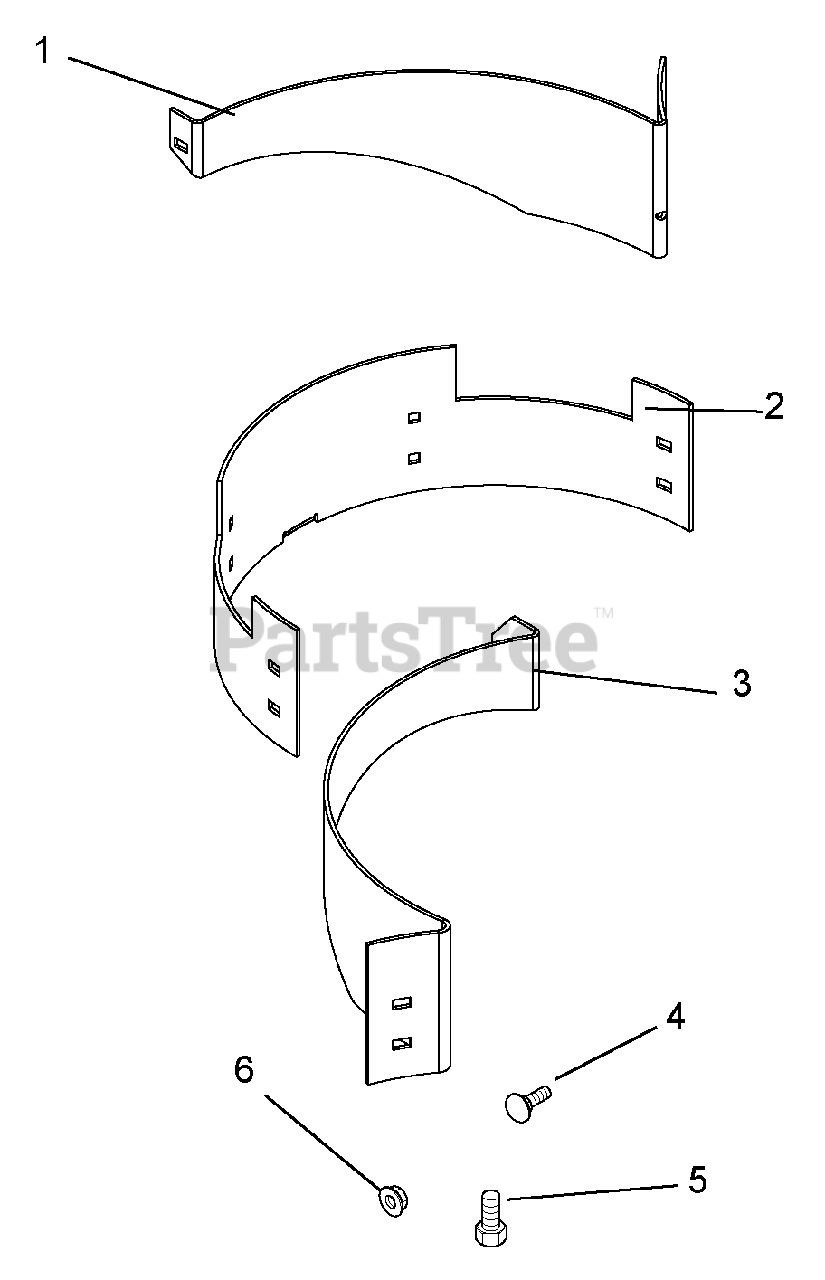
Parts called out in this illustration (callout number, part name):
1	BAFFLE-MULCH-LEFT REAR-44" RD
2	BAFFLE-MULCH-CENTER REAR-44"RD
3	BAFFLE-MULCH-RIGHT REAR-44" RD
4	@BLT-RDHDSQNK .31-18X.75 G5YZ
5	@BLT-HEX .31-18X.75 GR5 YWZC
6	@NUT-LK-TOP-FLG .31-18 YWZC
